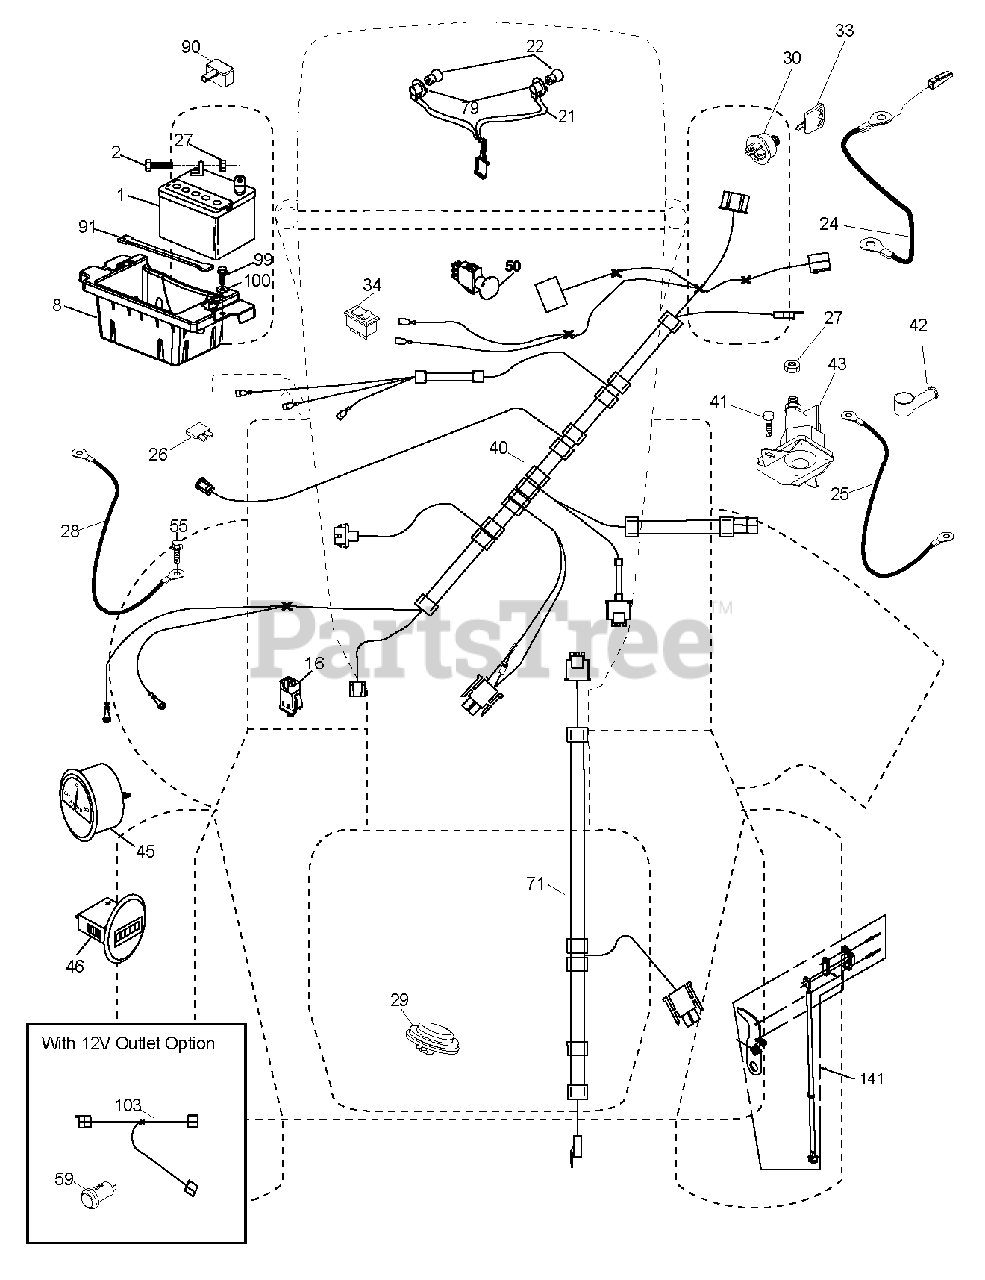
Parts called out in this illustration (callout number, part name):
1	Battery, Dry 30 Amp
2	BOLT.HEX.1/4.X.3/4.DICHROMATE
8	BOX.BATTERY.MOUNT.FRONT.LT
16	SWITCH INTERLOOK PUSH-IN
21	HARNESS.LIGHT W/4152J BULBS
24	CABLE.BATT.POS.WIRE.TG.DA SOL
25	CABLE.STARTER.6G.BL/RED.17.5
26	FUSE 20AMP
27	NUT
28	CABLE GROUND 6 GA 21" 90T BLK
29	SWITCH.SEAT.DELTA.OPC.
30	SWITCH.IGN.DELTA.W.LGH.ROS
33	KEY.CHAIN.BLISTER.PACK.GEN.USA
40	HARNESS.EFM.ROUND
41	SCREW
42	TERMINAL COVER
43	SOLENOID.W/BRASS.PLUNGER
45	AMMETER GAUGE ROUND SNAP-IN
46	HOURMETER.GAUGE.RNK.SNAPIN.LS
50	RB PTO.SWITCH.8 TERMINAL.BLACK
55	SCREW 5/16"
59	OUTLET.12-VOLT
71	HARNESS-CHASSIS SUB
79	BULB HOLDER ASM.
90	COVER.TERMINAL.BATTERY
91	STRAP.BATTERY.MOUNT.FRONT(2 2)
99	SCREW HEXWSHR 1/4-20X3/4
103	HARNESS.PIGTAIL.12V.OUTLET.
141	KIT.G700/G730.ROS 71750
